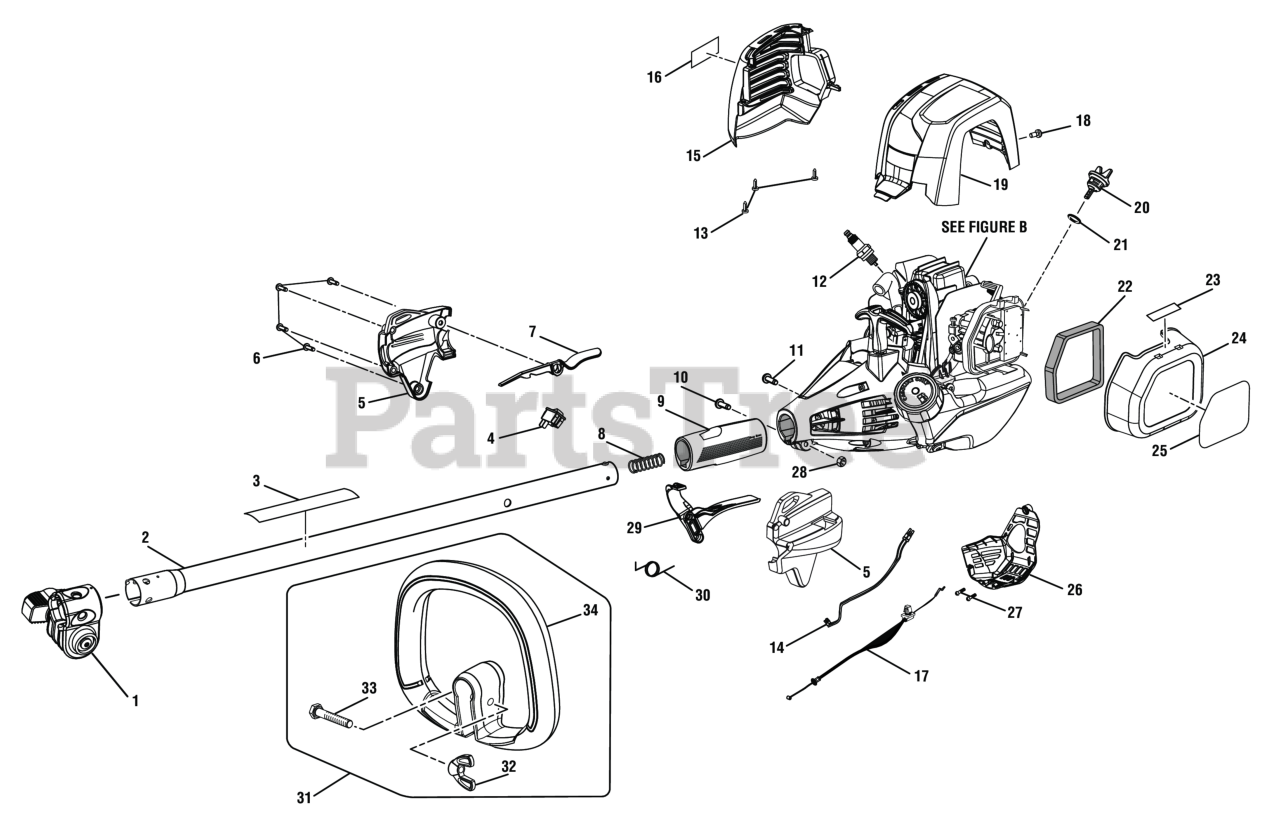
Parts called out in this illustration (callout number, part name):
1	Boom Clamp Assembly
2	Upper Boom Assembly (Inc. Key Nos. 1-2)
3	Warning Icon Label
4	Stop Switch (Momentary Contact)
5	Control Handle Assembly (Inc. Key No. 6)
6	Screw (M4 x 20 mm, T20 Torx Pan Hd. S.T.)
7	Trigger Lock
8	COMPRESSION SPRING
9	Rear Handle Grip
10	Screw (M6 x 20 mm, T27 Torx Button Hd.)
11	Screw (M4 x 8 mm, T25 Torx Pan Hd. T.F.)
12	Spark Plug (Champion RY4C)
13	Screw (M4 x 12 mm, T20 Torx Truss Hd.)
14	Lead Assembly
15	Muffler Housing (Inc. Key No. 16)
16	Warning Label (Combustion)
17	Throttle Cable
18	Shoulder Screw (M4 x 11 mm, T25 Torx Pan Hd.)
19	Top Cover
20	Oil Cap/Dipstick (Incl. key no. 12)
22	Air Filter
23	Choke Label
24	Air Filter Cover
25	Starting Label
26	CE Cover (Bottom Cover)
27	Screw (#6-19 x 1/2 in., Phillips Hd. T.F.)
28	Hex Nut (M6.3 x 1)
30	Torsion Spring (Throttle Trigger)
31	Front Handle Assembly
32	Wing Nut (1/4-20, Plastic)
33	Screw (1/4-20 x 40 mm, Cap Hex Hd.)
34	Front Handle
